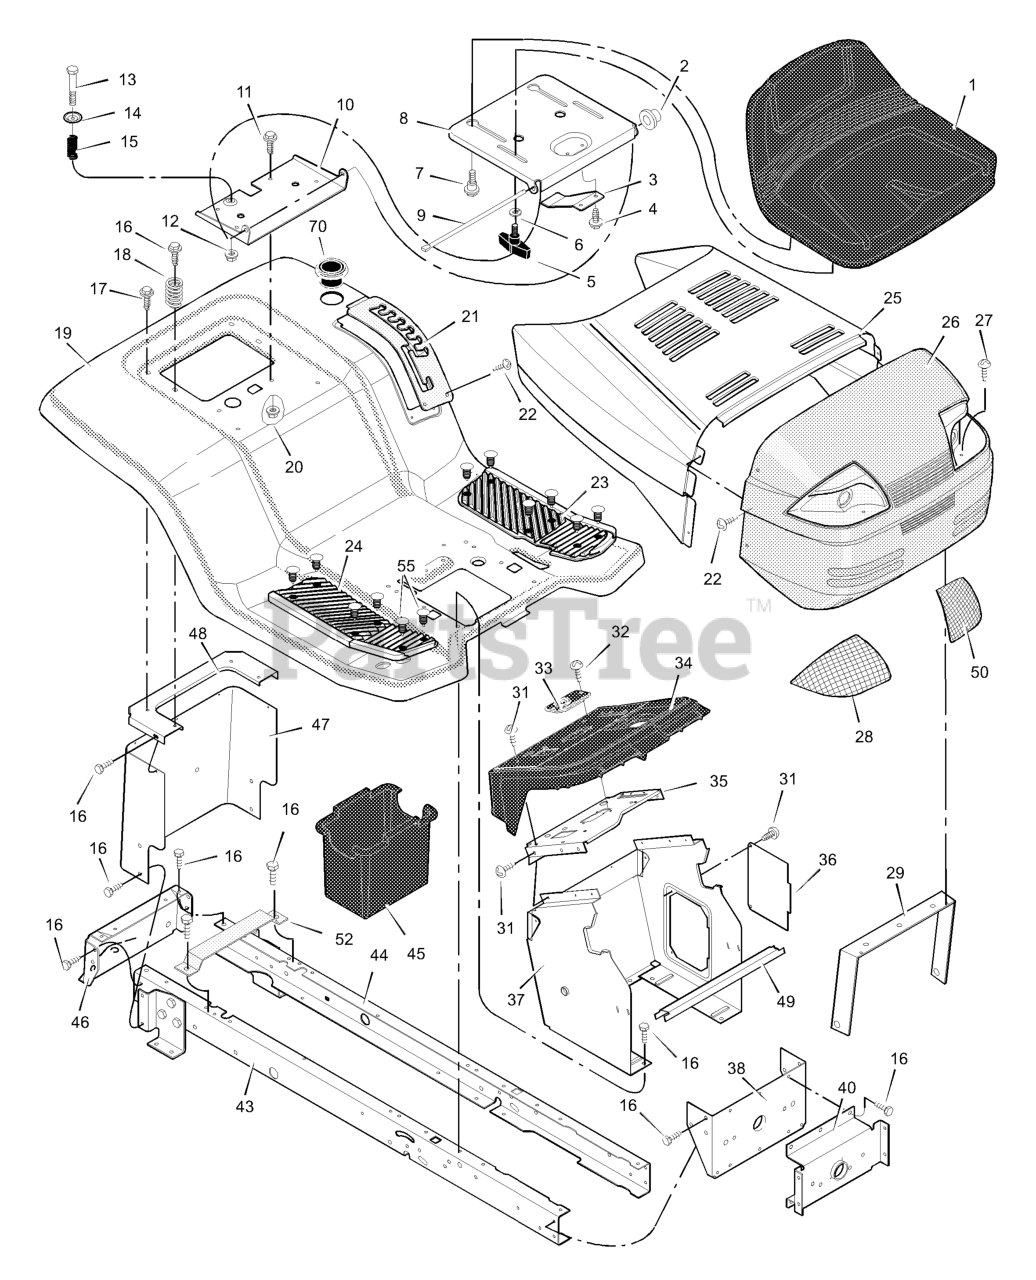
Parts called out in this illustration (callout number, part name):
2	Cap, Push On
5	Bolt, Wing
6	Washer
7	Bolt, Shoulder
8	Support, Seat
9	Rod, Pivot
10	Bracket, Pivot
11	Bolt
13	Bolt, Shoulder
15	Spring
19	Deck, Seat
20	Nut
21	Plate, Index
23	Mat, Left
24	Mat, Right
25	Hood
26	Grille Assembly
27	Screw
28	Lens, Right
29	Brace, Grille
30	Pin, Hair
31	Screw
33	Bearing, Steering
34	Dash (Grey)
35	Plate, Dash
36	Panel, Access
37	Support, Dash
38	Bracket, Rear Hanger
40	Axle, Hanger
43	Frame, Right
44	Frame, Left
45	Container, Battery
46	Plate, Hitch
47	Plate, Rear
48	Top, Rear Plate
50	Lens, Left
52	Support, Battery
55	Clip (Grey)
70	Holder, Cup
